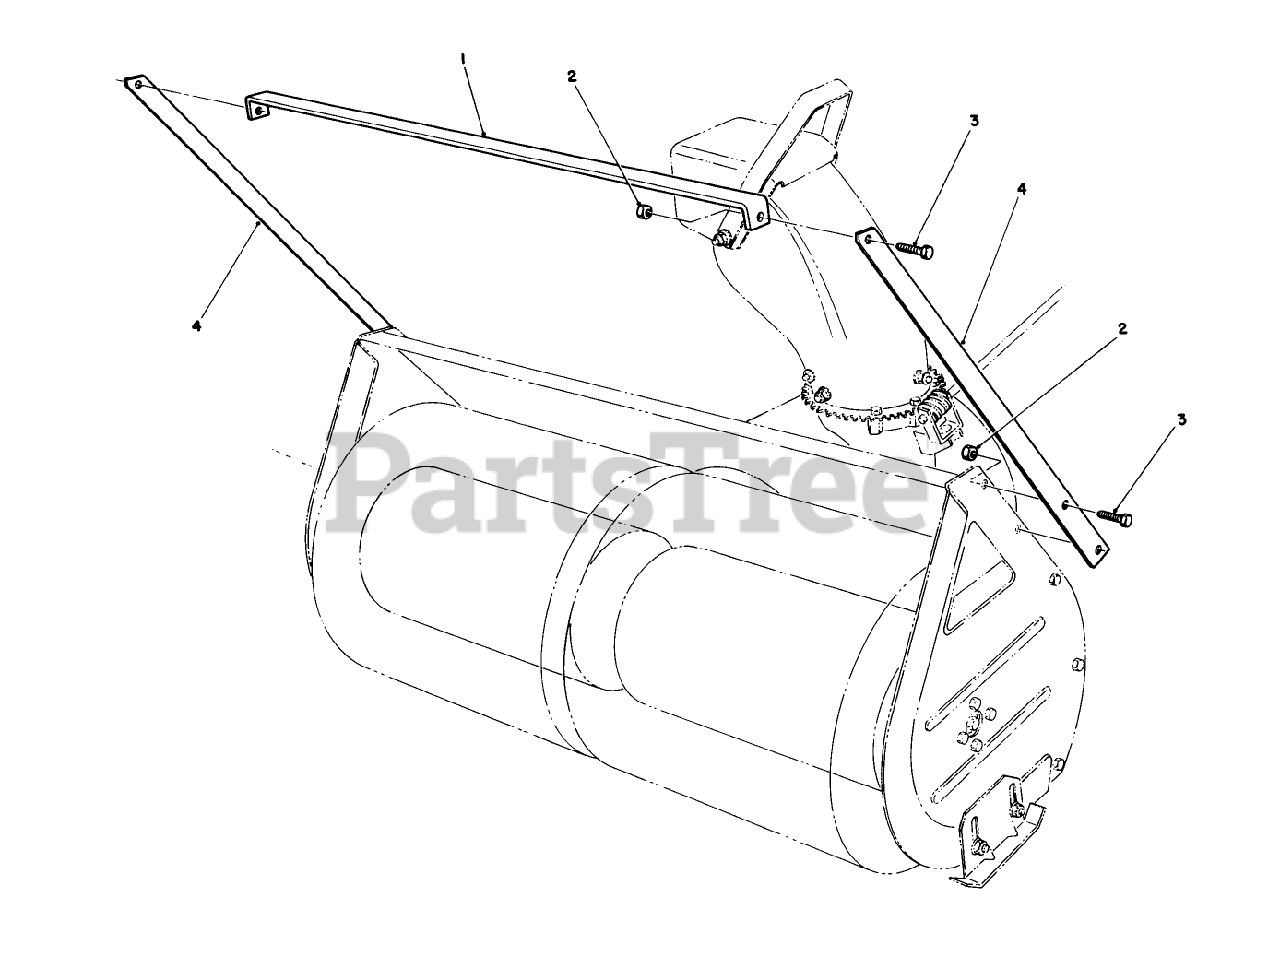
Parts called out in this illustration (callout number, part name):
1	32 TOP DRIFT BREAKER
2	NUT-LOCK, CONE
3	SCREW-HH
4	SIDE DRIFT BREAKER
